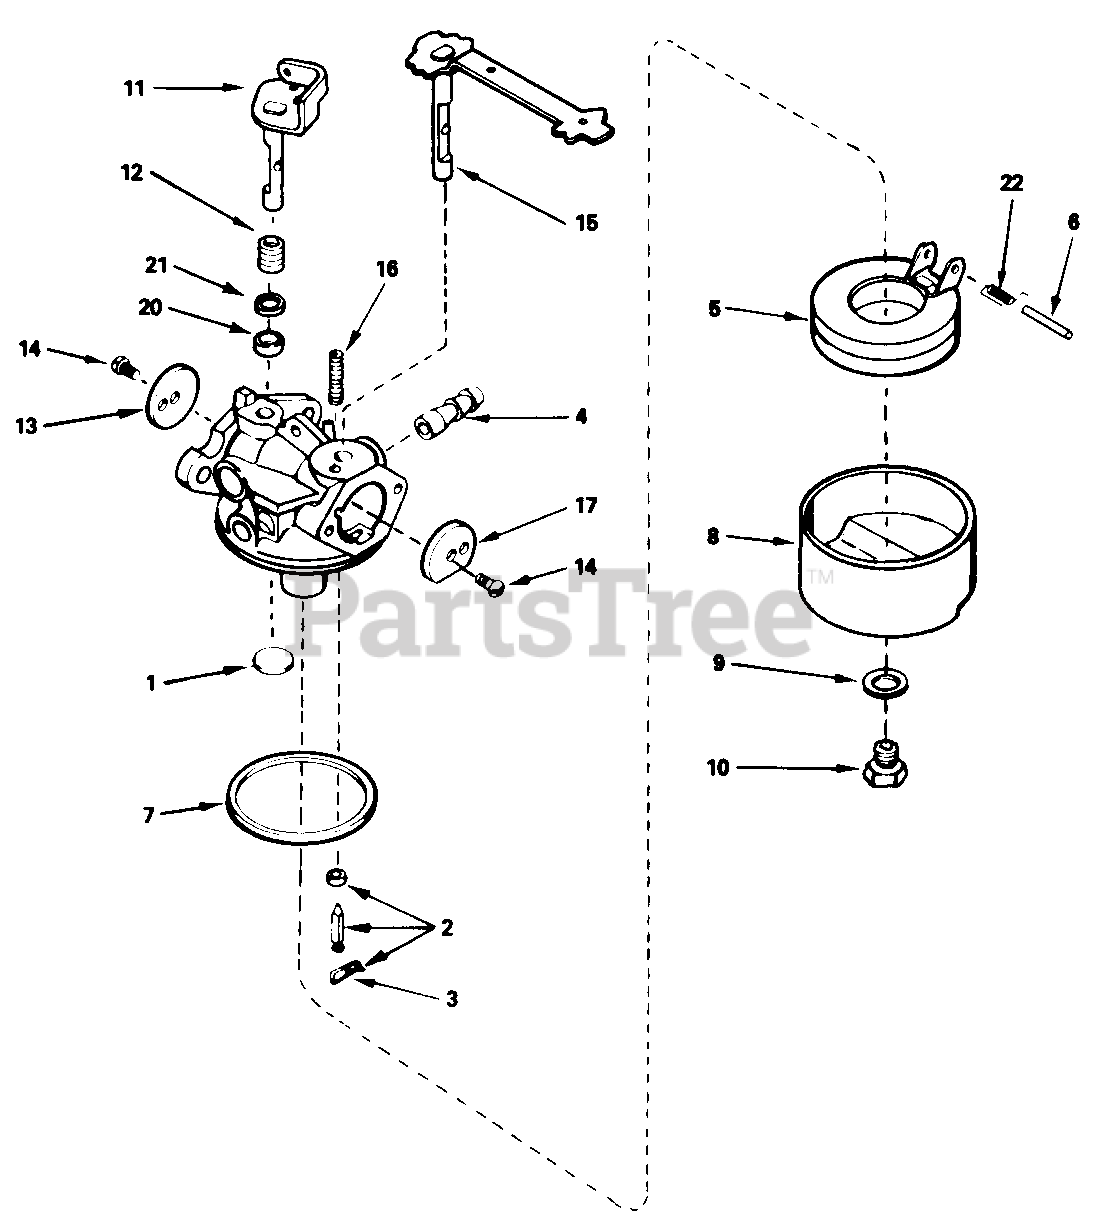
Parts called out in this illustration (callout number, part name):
1	Plug, Welch
2	Inlet Needle, Seat & Clip Ass'y.
3	Clip, Inlet Needle
4	Fitting, Fuel Inlet
5	Float, Carburetor
6	Shaft, Float
7	"O"-Ring, Bowl-to-Body
8	Bowl, Float
9	Gasket, Bowl-to-Body
10	Nut, Float Bowl
11	Shaft & Lever Ass'y., Throttle
12	Spring, Throttle Return
13	Shutter, Throttle
14	Screw, Throttle & Choke Shutter
15	Shaft & Lever Ass'y., Choke
16	Spring, Choke Positioning
17	Shutter Choke
20	Washer, Felt
21	Washer, Steel
22	Spring, Float Shaft
